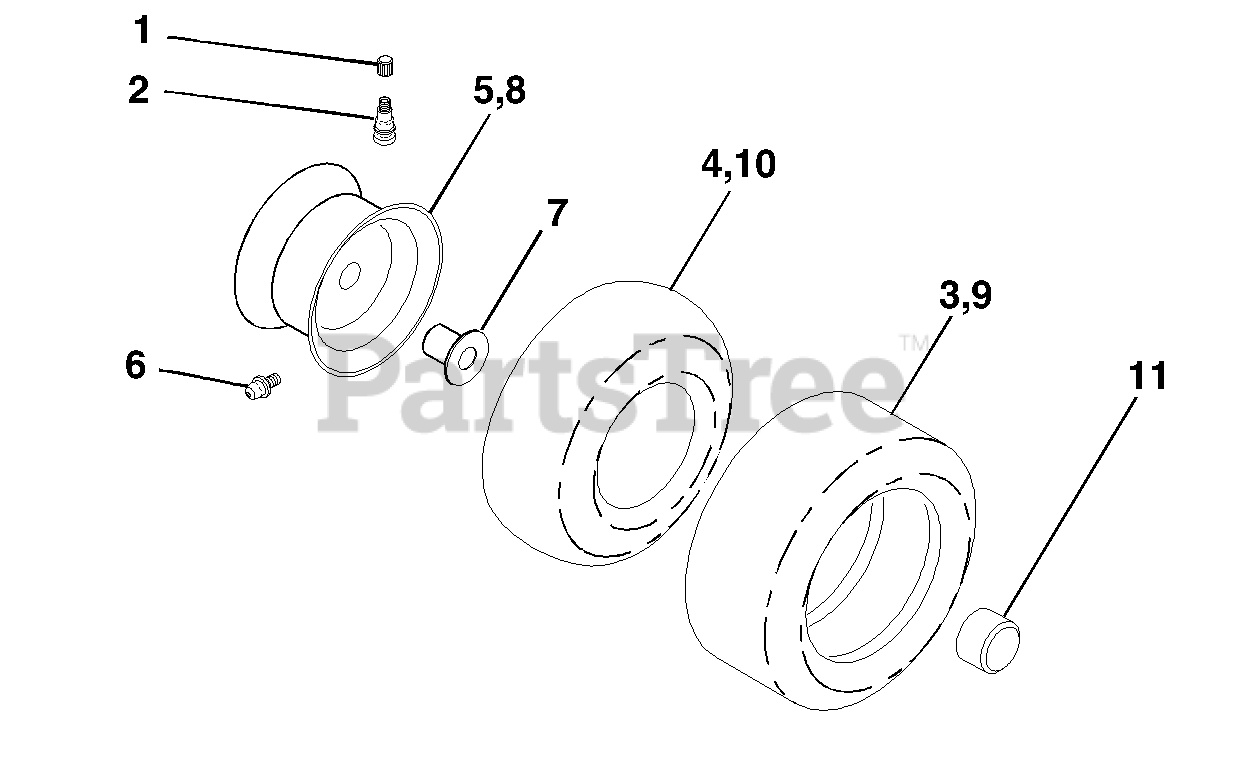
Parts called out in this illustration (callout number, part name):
1	Cap Valve Tire
2	Stem Valve
3	Tire F Ts 15 X 6 0 - 6 Service
4	Tube Front
5	Rim Asm 6"front White Service
6	Fitting Grease
7	Bearing Flange
8	Rim Asm 8"rear White Service
9	Tire R Ts 18x9.5-8 C Service
10	Tube Rear
11	Cap Axle Blk 1 50 X 1 00
